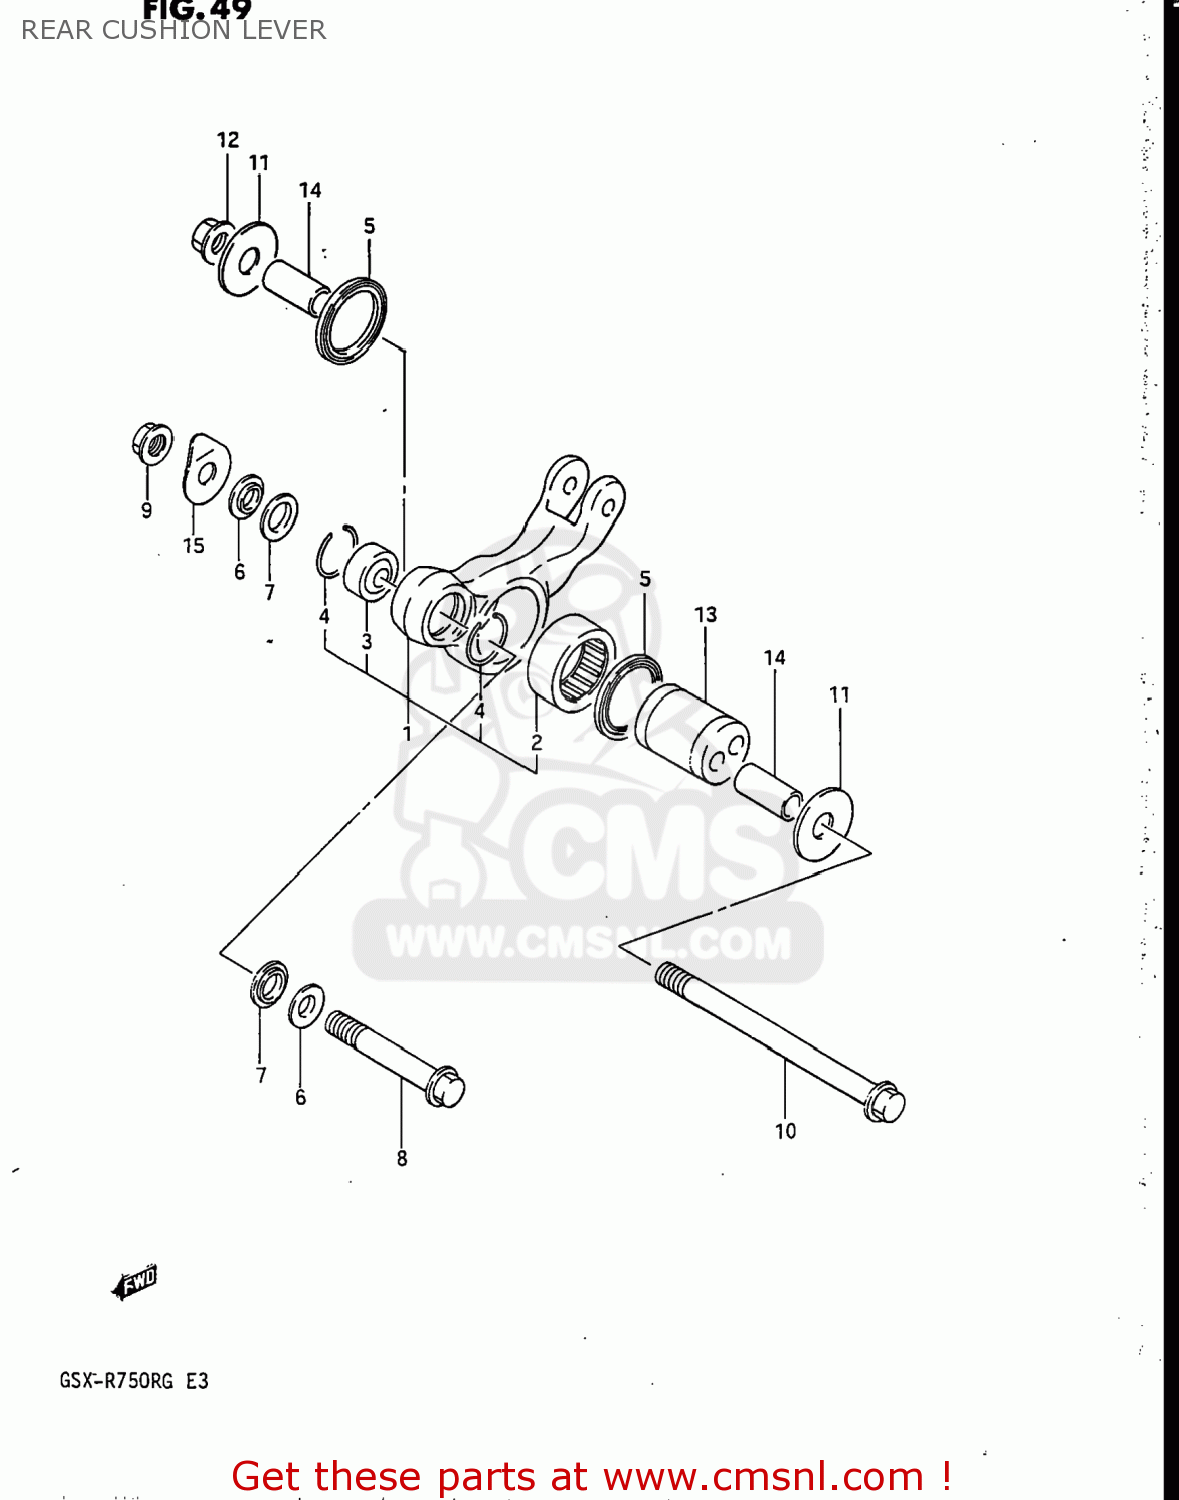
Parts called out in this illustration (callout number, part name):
1	LEVER SET,REAR CUSHION
2	BEARING(35X45X20)
3	BEARING(12X26X16)
4	RING,STOPPER
5	SEAL,INNER DUST
6	SPACER,RR CUSHION ROD
7	SEAL,RR CUSHION ROD DUST
8	BOLT,RR CUSHION LEVER FR
9	NUT 12MM
10	SHAFT
11	WASHER(12X40X2.5)
12	NUT 12MM
13	SPACER,REAR CUSHION ECCENTRIC
14	SPACER
15	SHIM,REAR CUSHION LEVER
